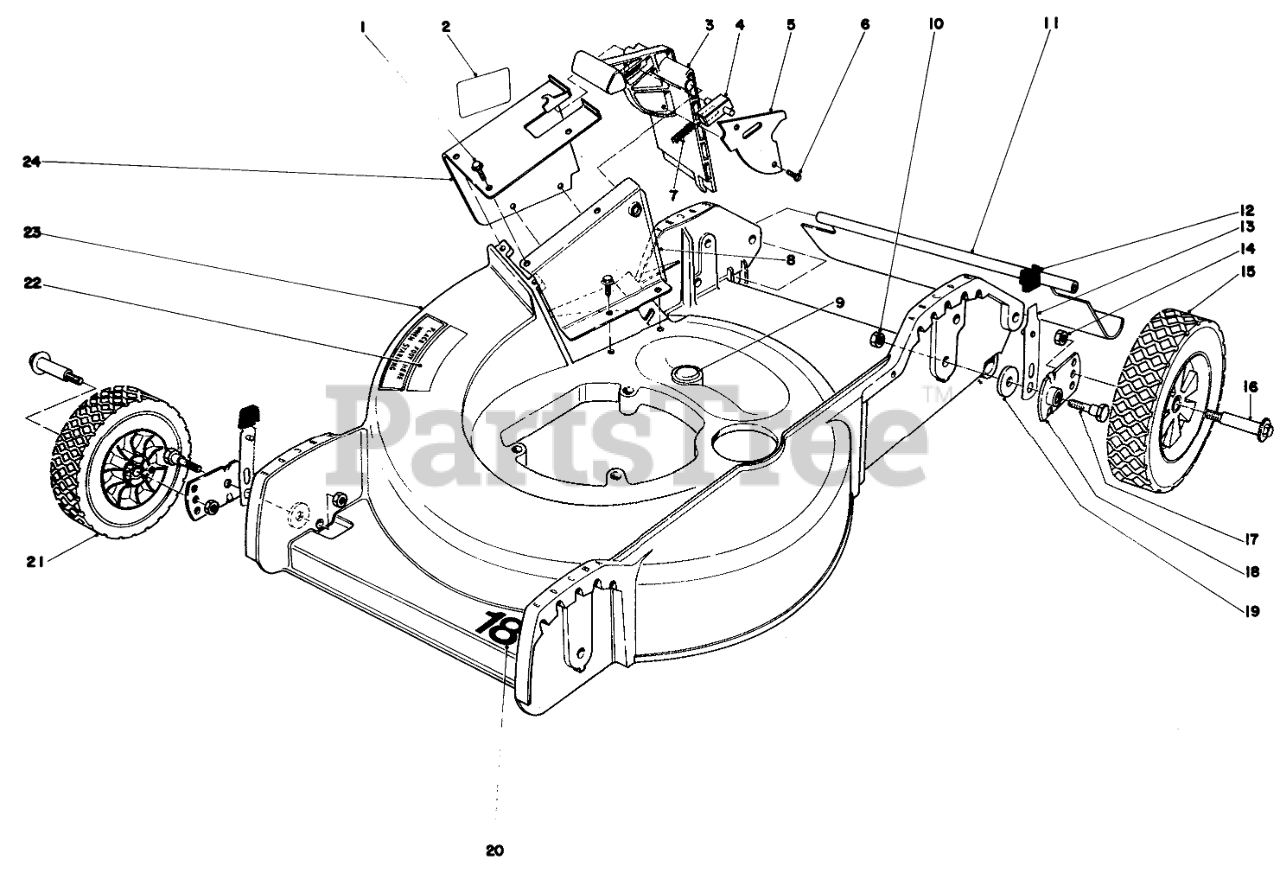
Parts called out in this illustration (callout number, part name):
1	SCREW
2	Decal-Danger
3	Door Mulching
4	Door Latch
5	Cover Door
7	Latch Spring
8	Inner Tunnel
10	Nut
11	SHIELD - TRAILING
12	KNOB-ARM
13	SPRING ARM ASM
14	Nut
15	Lever-Valve
16	BOLT-WHEEL
17	PIVOT SCREW
18	PIVOT ARM ASSY
19	PIVOT WASHER
20	Decal
21	WHEEL TIRE ASM 7 IN
22	Decal-Place Foot Here
23	Housing
24	Tunnel Outer
